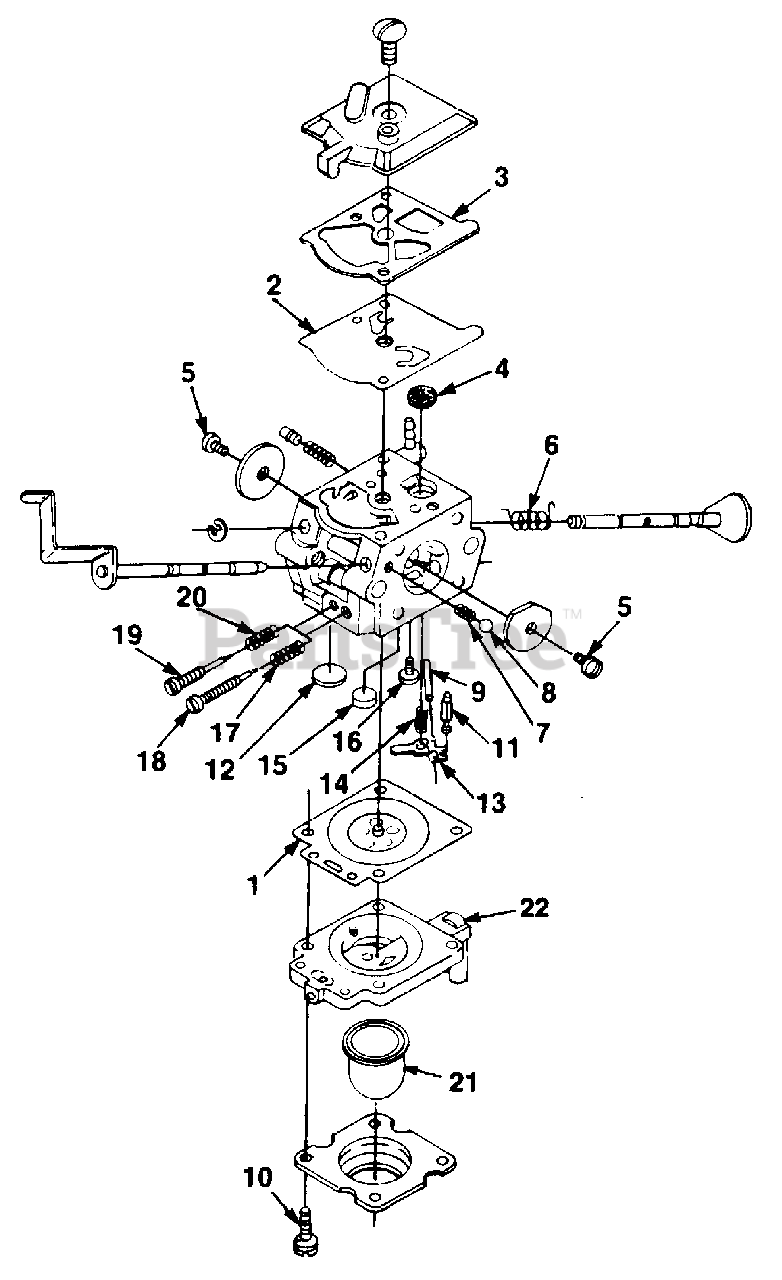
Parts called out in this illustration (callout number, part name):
1	REPAIR KIT (1-20)
2	REPAIR KIT (1-20)
3	REPAIR KIT (1-20)
4	REPAIR KIT (1-20)
5	REPAIR KIT (1-20)
6	REPAIR KIT (1-20)
7	REPAIR KIT (1-20)
8	REPAIR KIT (1-20)
9	REPAIR KIT (1-20)
10	REPAIR KIT (1-20)
11	REPAIR KIT (1-20)
12	REPAIR KIT (1-20)
13	REPAIR KIT (1-20)
14	REPAIR KIT (1-20)
15	REPAIR KIT (1-20)
16	REPAIR KIT (1-20)
17	REPAIR KIT (1-20)
18	REPAIR KIT (1-20)
19	REPAIR KIT (1-20)
20	REPAIR KIT (1-20)
21	PRIMER BULB (21)
22	PRIMER BASE (22)
